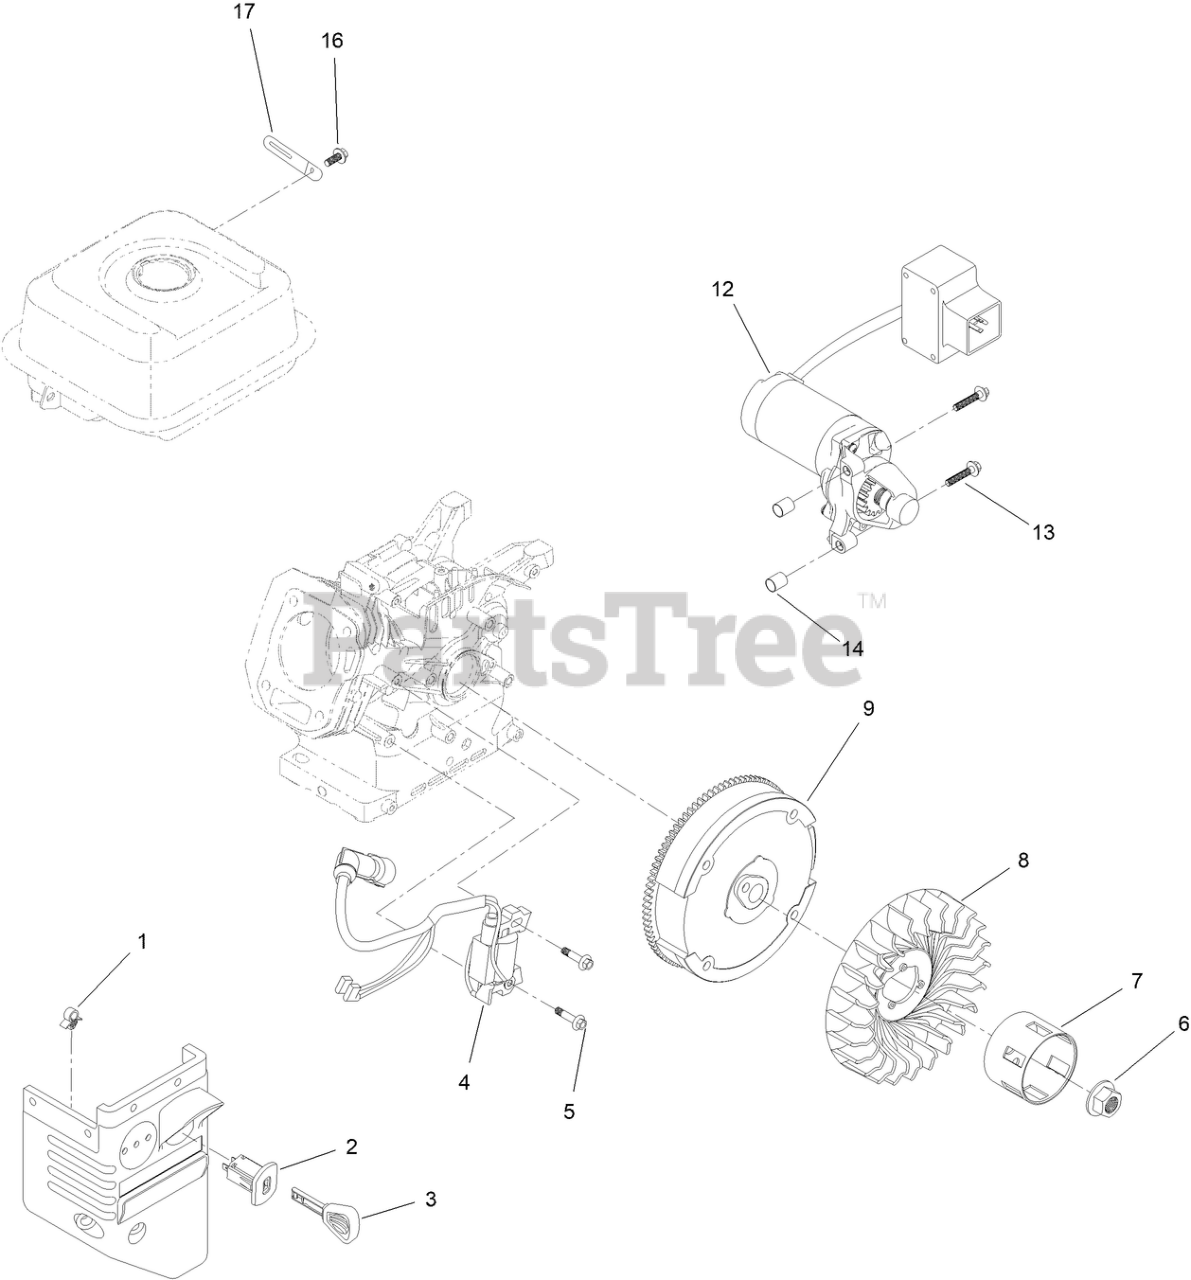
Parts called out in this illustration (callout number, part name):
2	SWITCH-KEY
4	IGNITION COIL ASM
5	SCREW-HHF
6	NUT-FLANGE
7	CUP-STARTER
9	FLYWHEEL
12	MOTOR-STARTER
13	SCREW-FLANGE
14	PIN-DOWEL
16	SCREW-HHF
17	CLIP-HARNESS, WIRE
